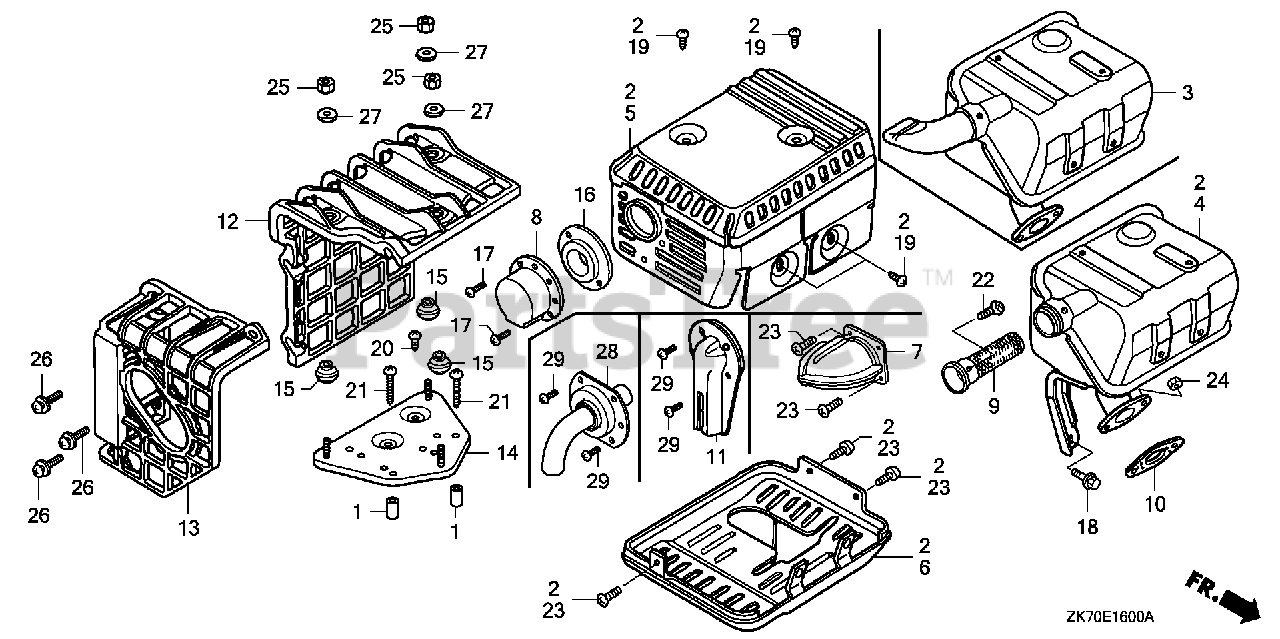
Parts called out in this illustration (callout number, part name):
4	MUFFLER (STD) Use up to Engine SN 1869307.
4	MUFFLER (ARRESTER) (SPARK ARRESTER TYPE)
5	PROTECTOR, MUFFLER (STD) (BLACK)
9	ARRESTER, SPARK
10	GASKET, MUFFLER
19	SCREW, TAPPING (5X8)
22	SCREW, TAPPING (4X6) (TO INSTALL OPTIONAL SPARK ARRESTER)
24	NUT, HEX. (8MM)
